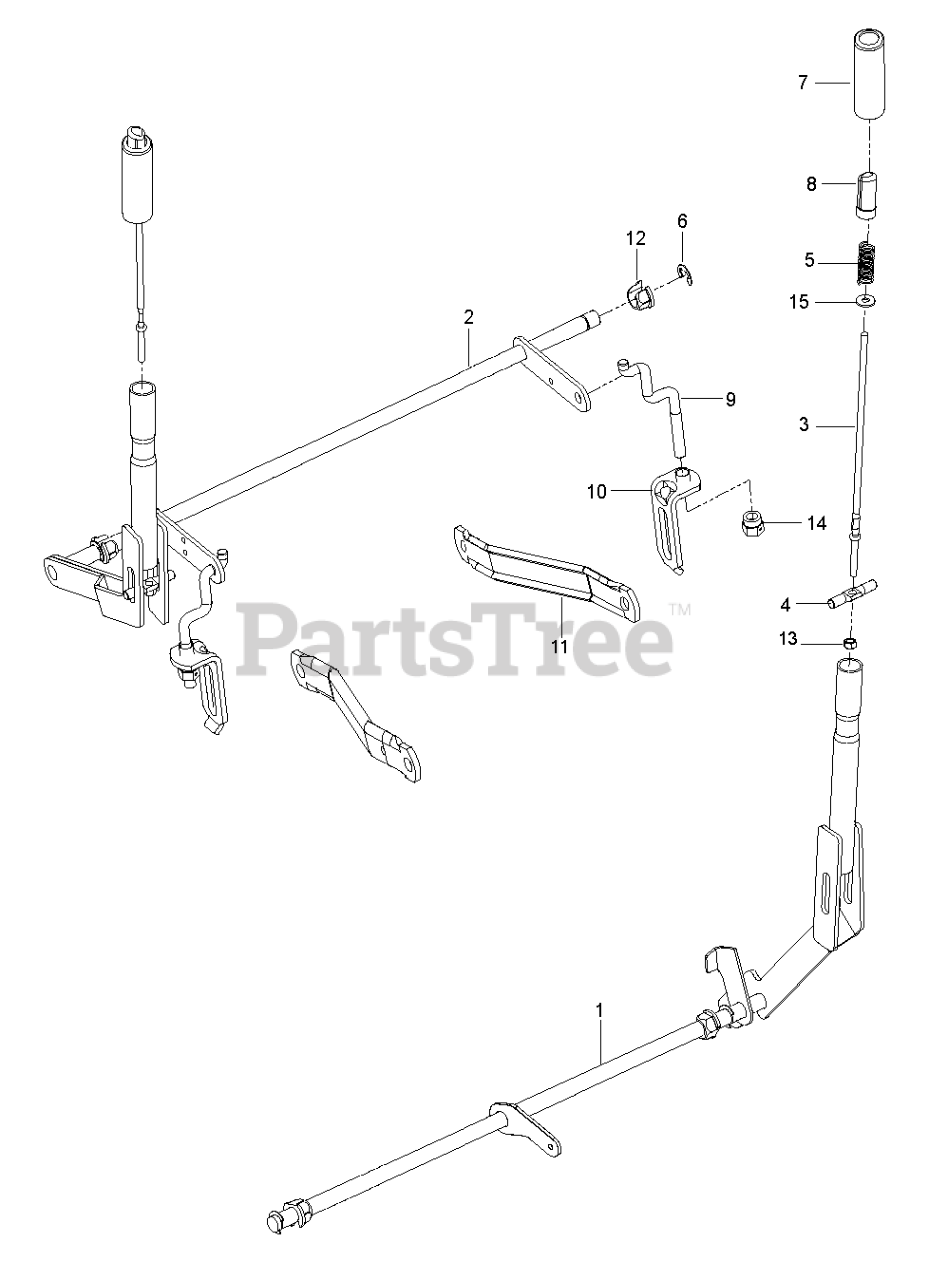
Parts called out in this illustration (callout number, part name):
1	SUBASM.SHAFT.BRAKE.WLDMNT.MED
2	DECK.LIFT.PNT.WELDMENT.RZ.BLK
3	ROD, HANDLE RELEASE
4	ROD LATCH RELEASE
5	SPRING, COMPRESSION
6	RETAINING RING LT
7	GRIP, HANDLE, BLACK 4"
8	BUTTON, PUSH, BLACK
9	LINK, REAR SUSPENSION
10	ASSEMBLY, BRKT LINK
11	ARM.SUSPENSION.MOWER
12	PLASTIC NUT
13	NUT.1/4-20.HEX.NYLOC.ZD
14	NUT, LIFT LINK 7/16-20
